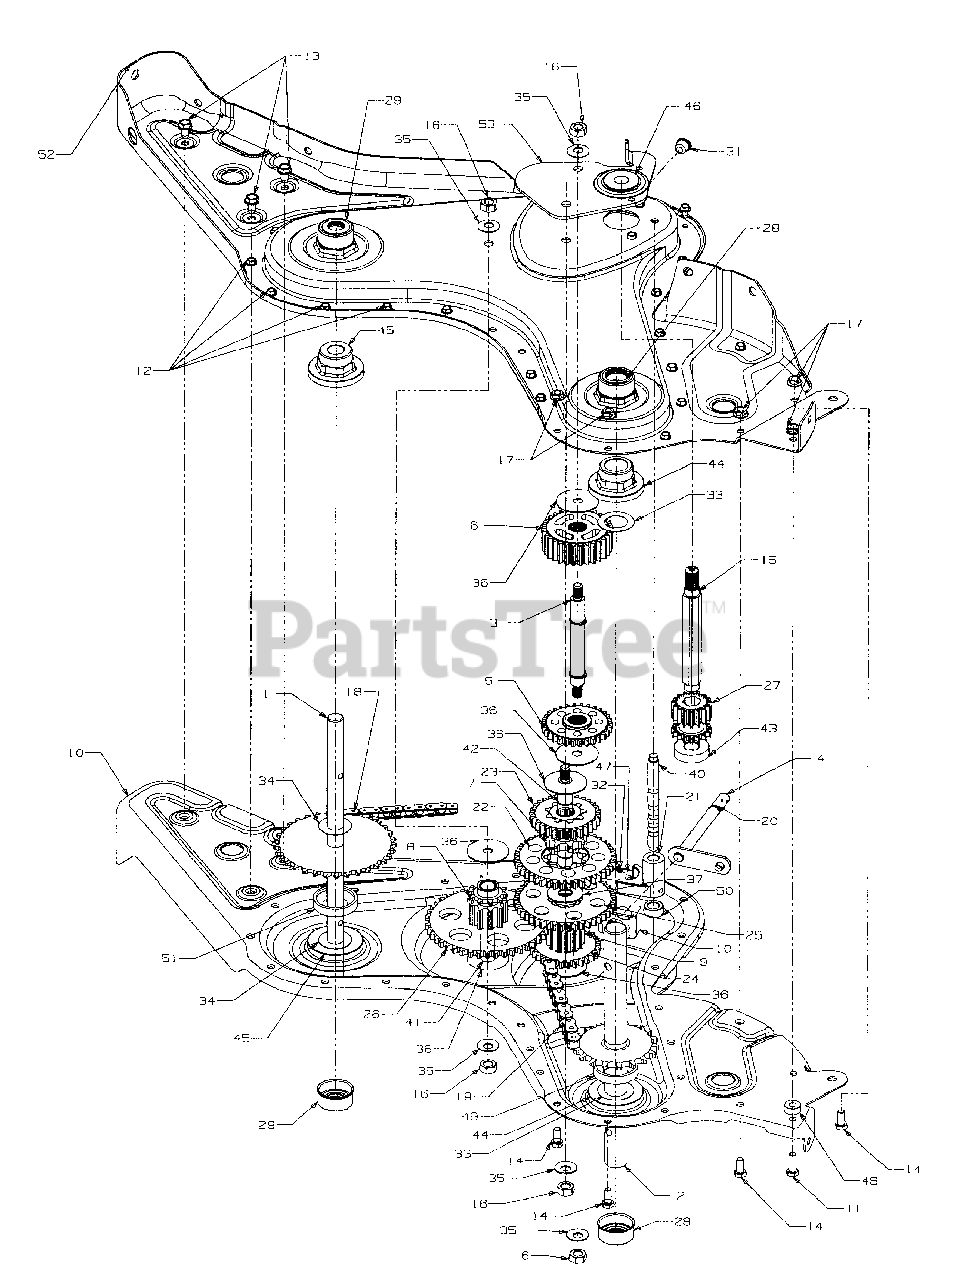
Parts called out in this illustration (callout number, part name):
1	Wheel Shaft Ass'y: 33T
2	Tine Shaft Ass'y: 18T
3	Jack Shaft Ass'y
4	Input Shaft Ass'y
5	Rev. Idler Gear Ass'y: 30T
6	Ftine Idler Gear Ass'y: 30T
7	Tine Input Sprocket Ass'y: 9T
8	Wheel Input Sprocket Ass'y: 10T
9	Gear Ass'y: 11 T
11	Hex Bolt 5/16-18 x 1" Lg.
12	Hex S-Tap Scr. 1 /4- 20 x .5"
13	Hex S-Tap Scr. 5/16-18 x .625"
14	Hex Bolt 5/16-18 x .75"
15	Input Shaft
16	Hex Nut 7/16-20
17	Flange Nut 5/16-18
18	#420 Chain 1 /2 Pitch x 50 Links
19	#50 Chain 5/8 Pitch x 54 Links
20	Snap Ring
21	Shifting Fork
22	Spur Gear 44T
23	Spur Gear 30T
24	Spur Gear 30T
25	Spur Gear 44T
26	Spur Gear 44T
27	Spur Gear 16T
28	Seal 1.0 Shaft
29	Seal .75 Shaft
31	Taper Cap Ring
32	Compression Spring .50" Lg.
33	Thrust Wash. 1.03" I.D. x 1.62"
34	Fl-Wash.76" I.D. x 1.5" O.D.
35	Bell-Wash.45" I.D. x 1.0"
36	Thrust Wash. .445 x 1.92 x .060
37	Fl-Wash 635" I.D. x 1.59 O.D.
40	Detent Shaft 1/2" Dia.
41	Jack Shaft .625 x 2.385
42	Jack Shaft .625 x 5.0
43	Ball Bearing
44	Flange Bearing 1.0 x 2.5 x 1.38
45	Flange Bearing .75 x 2.5 x 1.38
46	Ball Bearing. 6692 x 5745 x .466
47	Detent Ball .250
48	Spacer.315
49	Spacer 1.0 LID x 2.0 O.D. x .440
50	Spacer.505 I.D. x .88 O.D. x
51	Spacer.75 x 2.0 x .50
53	Gear Positioner Bracket
